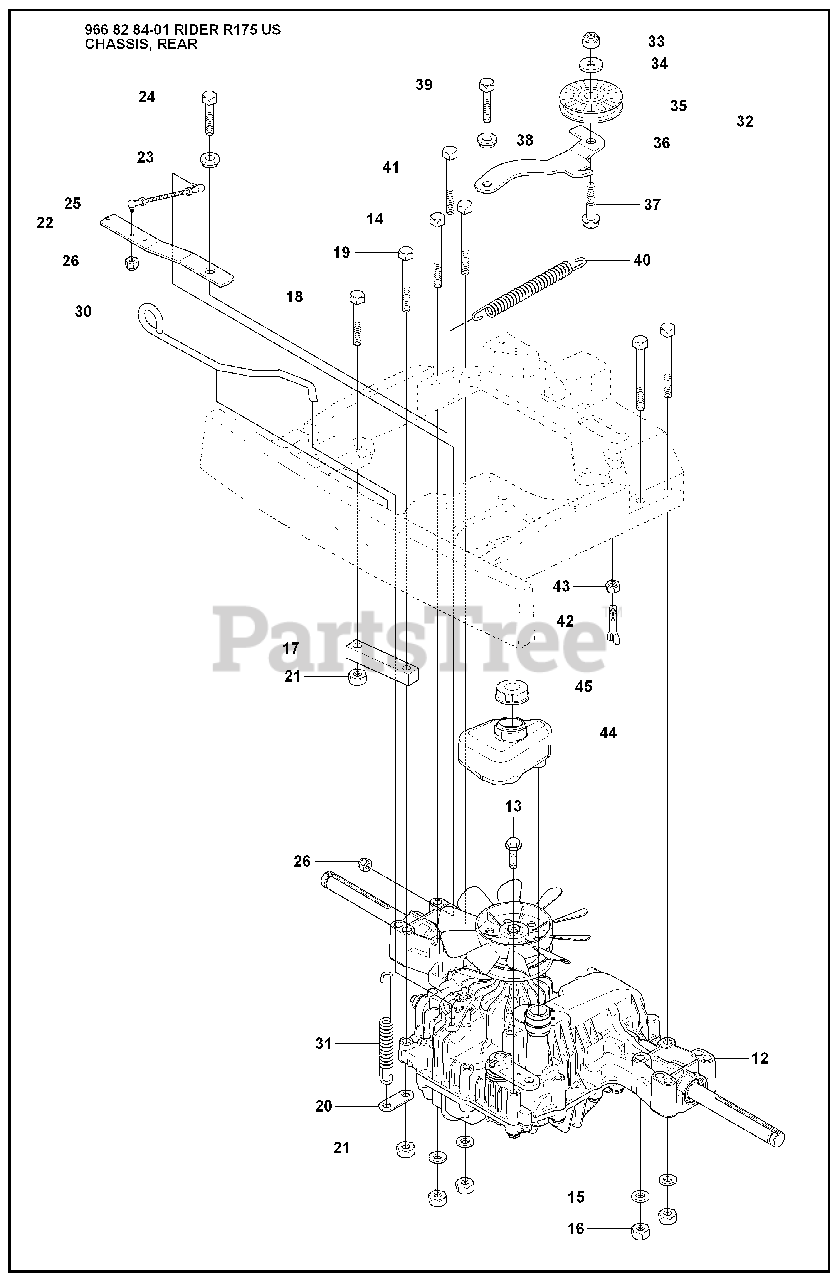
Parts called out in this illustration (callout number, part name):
12	HYDROSTAT 7A646024070
15	WASHER BRB 8.4X17
16	NUT
21	NUT
23	WASHER
24	SCREW 8X20
26	LOCKNUT M5
33	TENSIONER
35	SCREW
37	LOCKNUT M8
38	WASHER
39	SCREW 8X20
43	NUT
45	TANK CAP
